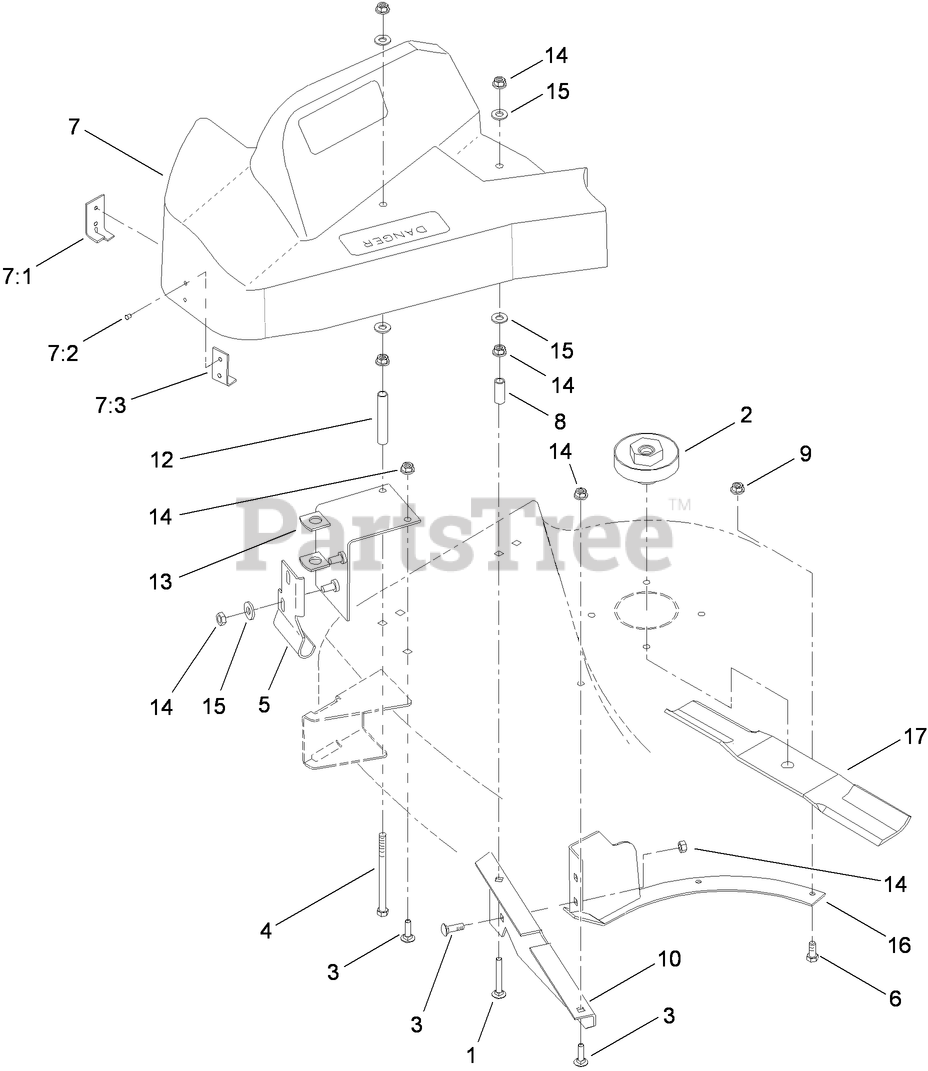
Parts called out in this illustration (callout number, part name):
1	SCREW-CARR
2	PULLEY
3	SCREW-CARR
4	SCREW-CARR
5	BRACKET-PIVOT
6	SCREW-HH
7	BELT SHIELD ASM
7:1	BRACKET-SUPPORT, SHIELD
7:2	RIVET-POP
7:3	BRACKET-SUPPORT, SHIELD
8	TUBE-LATCH
9	NUT-LOCK, NI
10	BAFFLE-REAR
12	TUBE-SPACER
13	PIVOT-BRACKET
14	NUT-LOCK, NI
15	WASHER-PLAIN
16	RING-BAGGING, RH
17	BLADE-LIFT, HIGH
